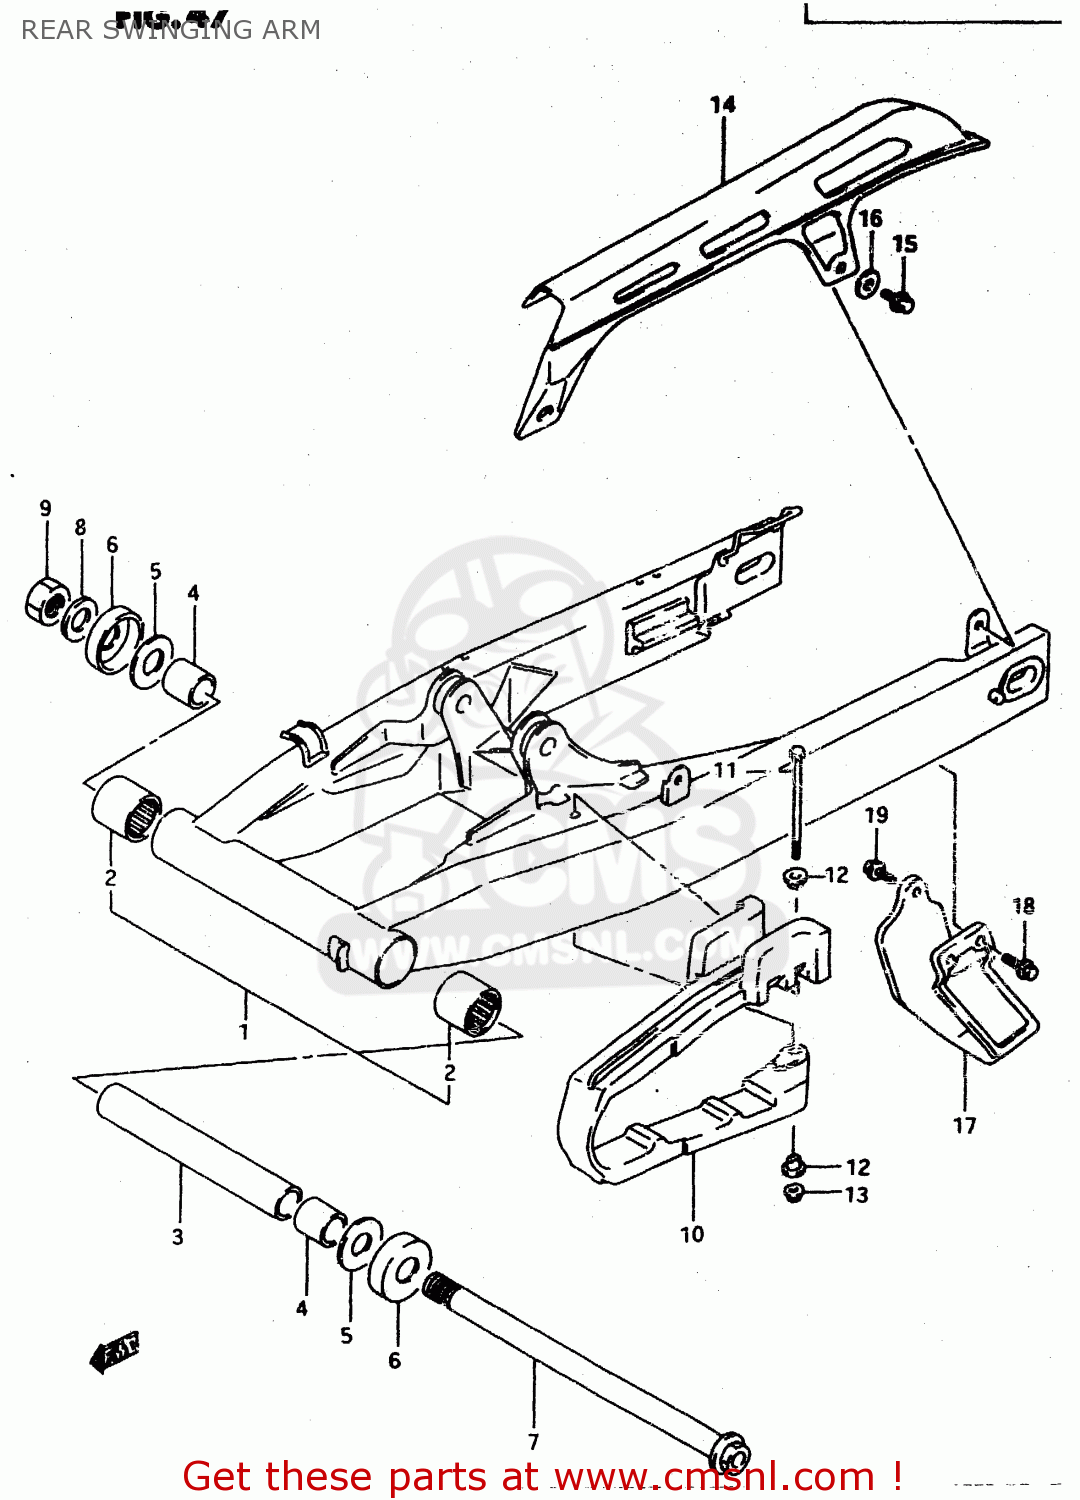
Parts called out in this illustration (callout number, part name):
1	SWING ARM ASSEMBLY,REAR
2	BEARING(22X29X20)
3	SPACER,RR SWGARM PIVOT CTR
4	SPACER,RR SWGARM PIVOT
5	WASHER
6	SEAL,RR SWGARM PIVOT DUST
7	SHAFT,RR SWINGINGARM PIVOT
8	WASHER
9	NUT 16MM
10	BUFFER,CHAIN TOUCH DEFENSE
11	BOLT,TOUCH DEFENSE FTG
12	WASHER
13	NUT
14	CASE,CHAIN
15	BOLT
16	WASHER
17	GUIDE,CHAIN
18	BOLT
19	BOLT
